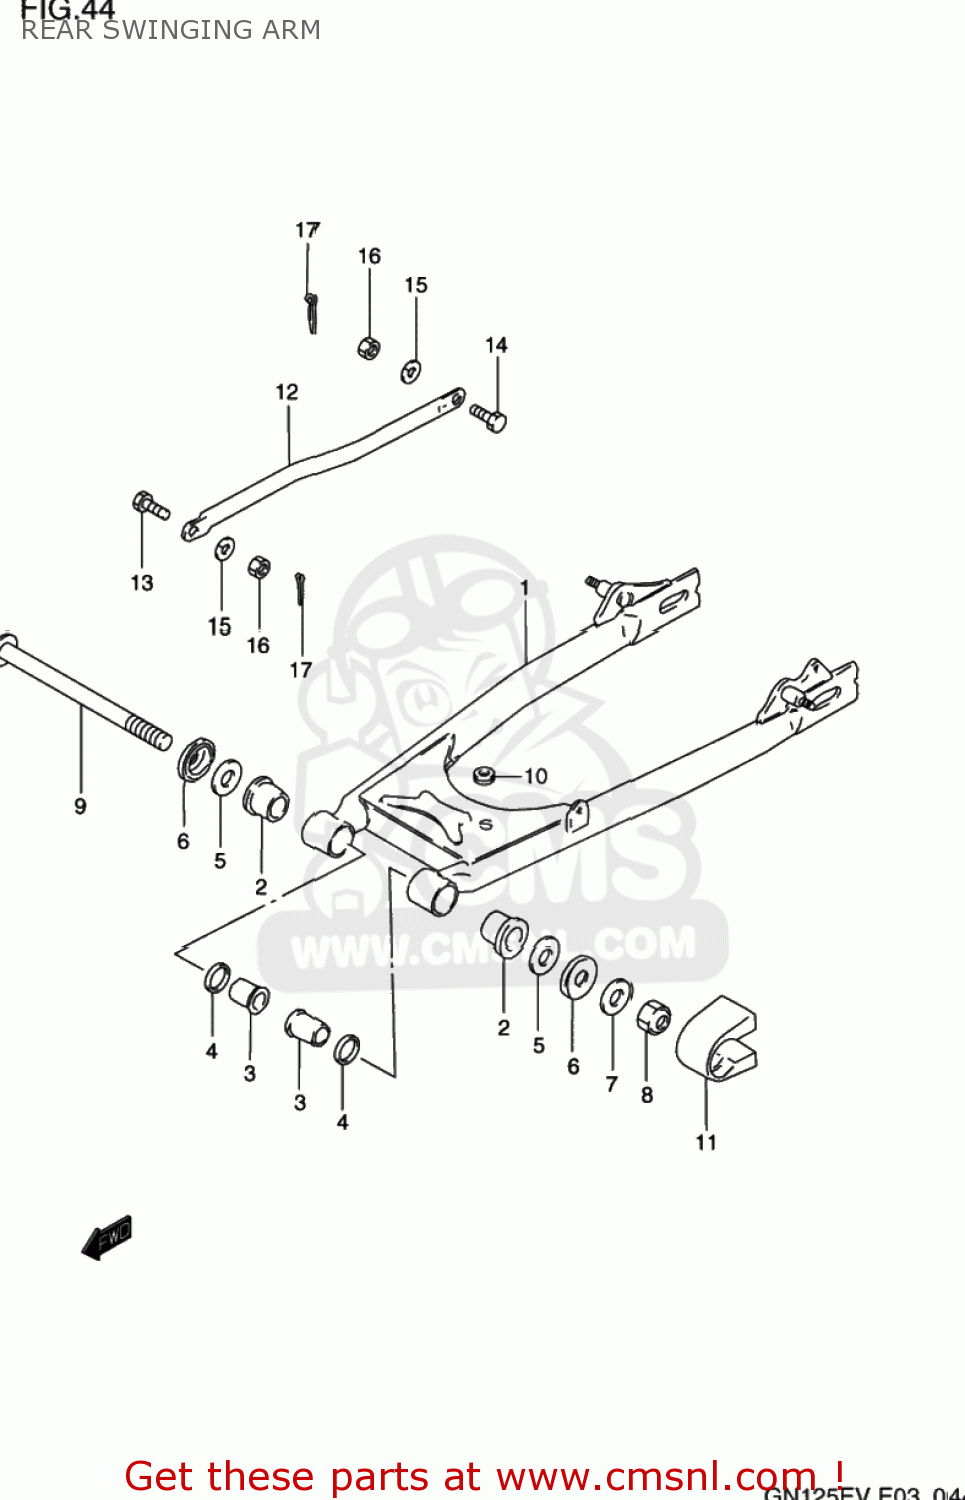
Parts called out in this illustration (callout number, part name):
1	SWINGINGARM ASSY,RR
2	BUSH,RR SWINGING ARM PIVOT
3	SPACER,RR SWGARM PIVOT
4	SEAL,OIL(20X27X5)
5	WASHER
6	CVR,RR SWGARM DUST SEAL(OD:40)
7	WASHER
8	NUT 14MM
9	SHAFT,RR SWINGINGARM PIVOT
10	CUSHION
11	BUFFER,CHAIN TOUCH DEFENSE
12	LINK,RR TORQUE
13	BOLT(8X22.5)
14	BOLT(8X26.5)
15	WASHER,LOCK
16	NUT
17	PIN 20X20
